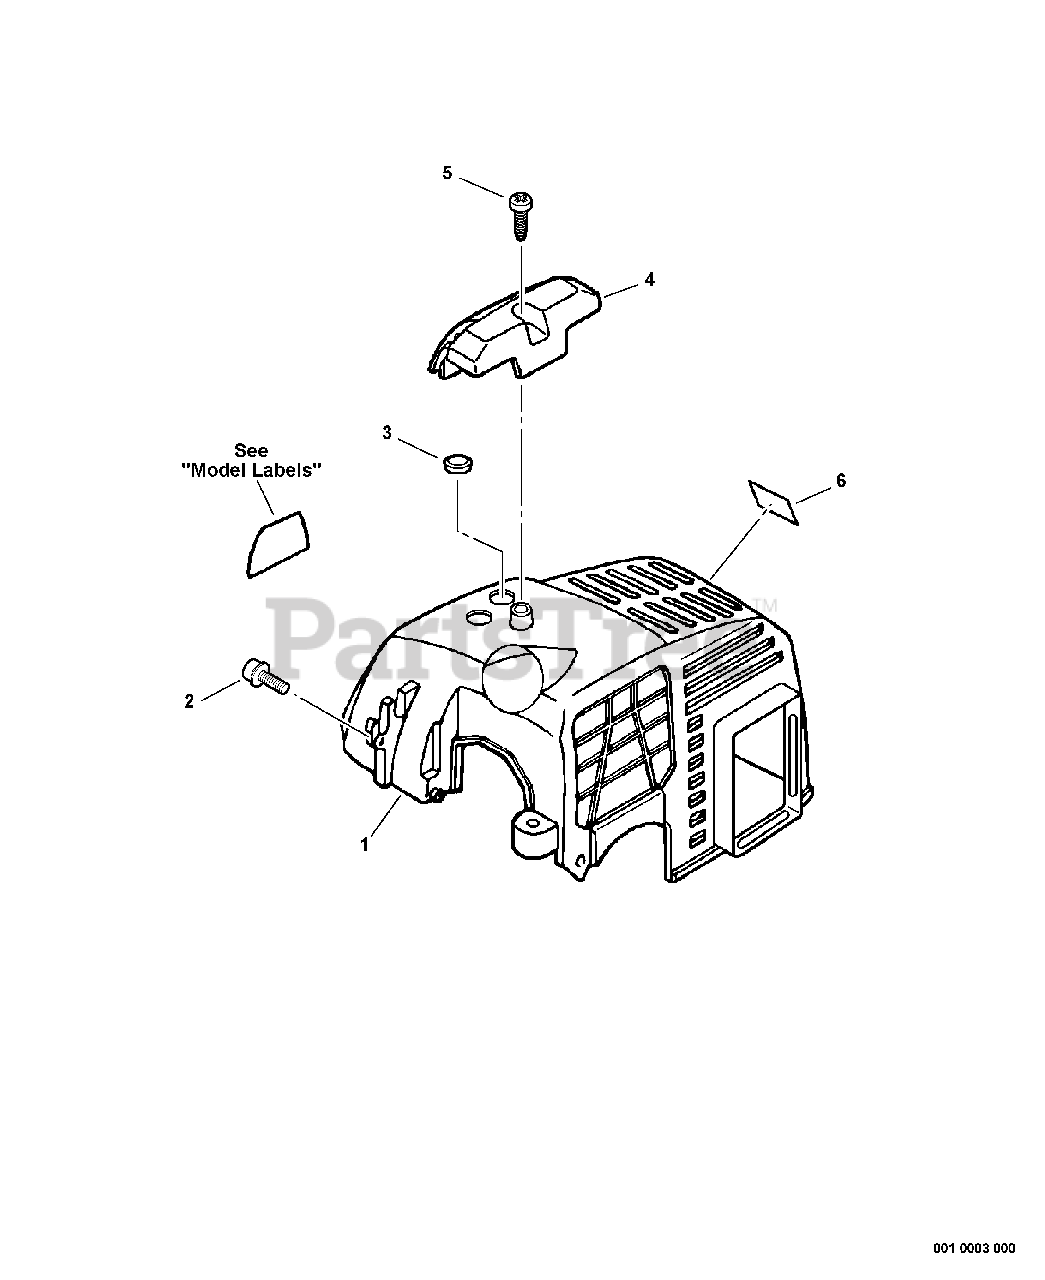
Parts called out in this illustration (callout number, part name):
1	COVER, ENGINE
2	SCREW - 4X12 -- TAPPING
4	GUARD, TOP - GRAY
5	SCREW - 5X16 -- TAPPING
6	LABEL - HOT SURFACE
